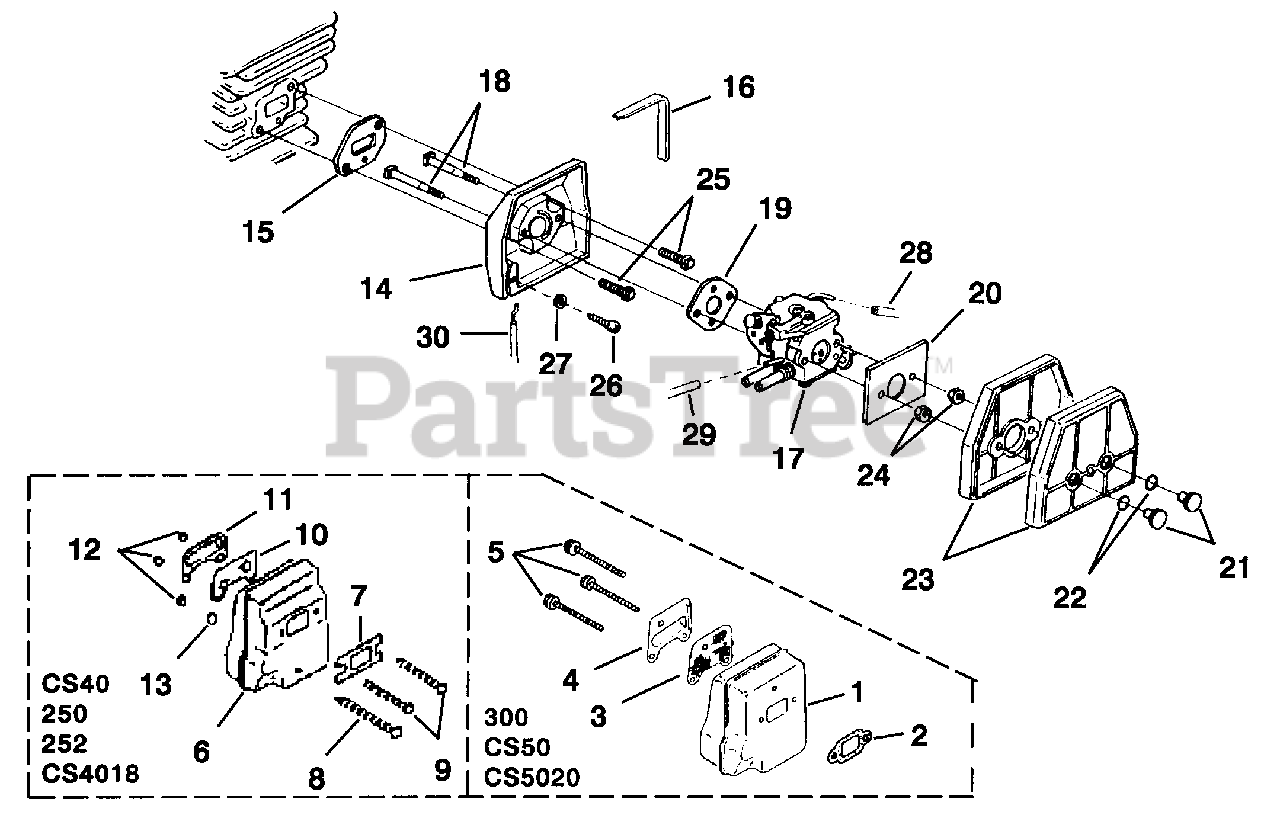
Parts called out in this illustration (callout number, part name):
1	MUFFLER - Complete
2	GASKET Muffler
3	SCREEN- Spark Arrestor
4	COVER- Exhaust
6	MUFFLER - Complete
7	GASKET Muffler
8	SCREW- Square Hd. (10-32 x 2 1/2)
9	SCREW- Square Hd. (10-32 x 2 1/4)
10	SCREEN-Spark Arrestor
11	COVER- Exhaust
12	NUT Locking (10-32)
13	WASHER- Flat (#12)
14	SPACER-Carburetor
15	GASKET- Carburetor Spacer
16	FOAM- Adhesive
17	CARBURETOR W/AIR FILTER (Walbro)
18	SCREW- Carburetor Retainer
19	GASKET Carburetor
20	RETAINER PLATE
21	RETAINER NUT Filter
22	"O" RING
23	AIR FILTER
24	NUT Hex (8-32)
25	SCREW Mach. Hex Hd. (8-32 x 7/8")
26	SCREW Thread Form (6-19 x 5/8")
27	WASHER Flat (#6)
28	TUBING-Rubber (9")
29	TUBING- Rubber (4 3/4")
30	CABLE Throttle
